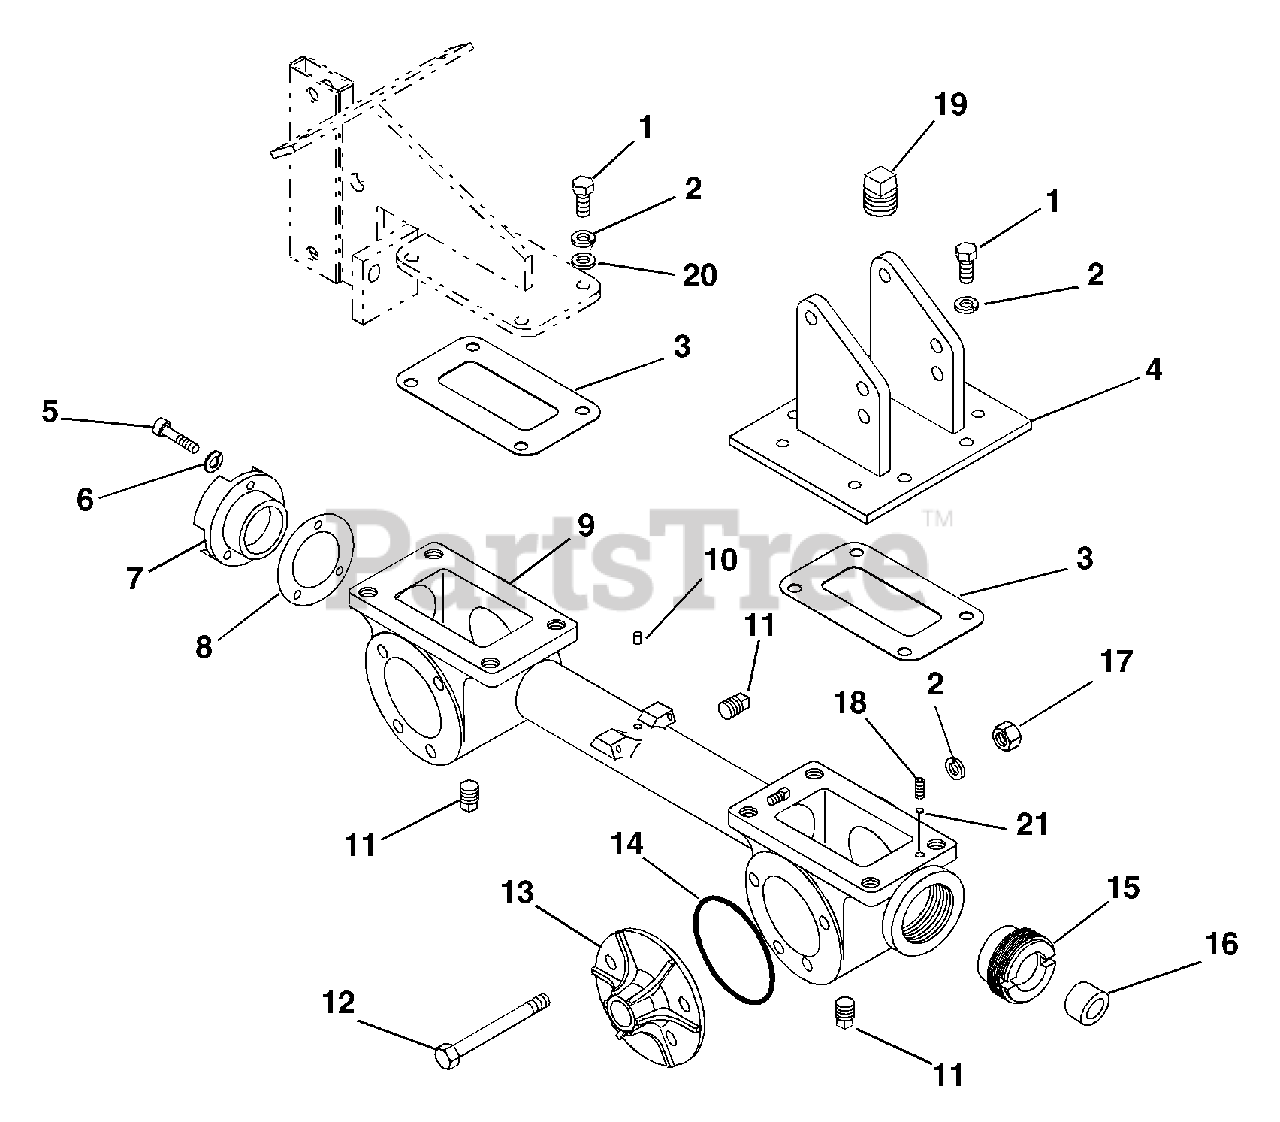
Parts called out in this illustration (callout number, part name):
1	@BLT-HEX .31-18X1.00 GR5 YWZC
2	@WSHR-LK .31X.078 REG YWZC
4	HANDLEBAR MOUNT
5	SCR-CAP.25-20X.75 SKT HD
6	@WSHR-LK .25X.062 REG YWZC
7	REAR CAP
8	GASKET - REAR CAP
9	GEAR CASE
10	BREATHER
11	PIPE PLUG, 1/4 NPT
12	@BLT-HEX .31-18X3.50 GR5 YWZC
13	AXLE HOUSING
14	O-RING 3.625X3.875X.135
15	ADJUSTMENT PLUG
16	SEAL .750X1.250X.136
17	@NUT-HEX .31-18 YWZC
18	SCR-SET .25-20X.25 SKHCUPDL
19	PIPE PLUG
20	@WSHR-FL-STL.344X.688X.065YWZC
